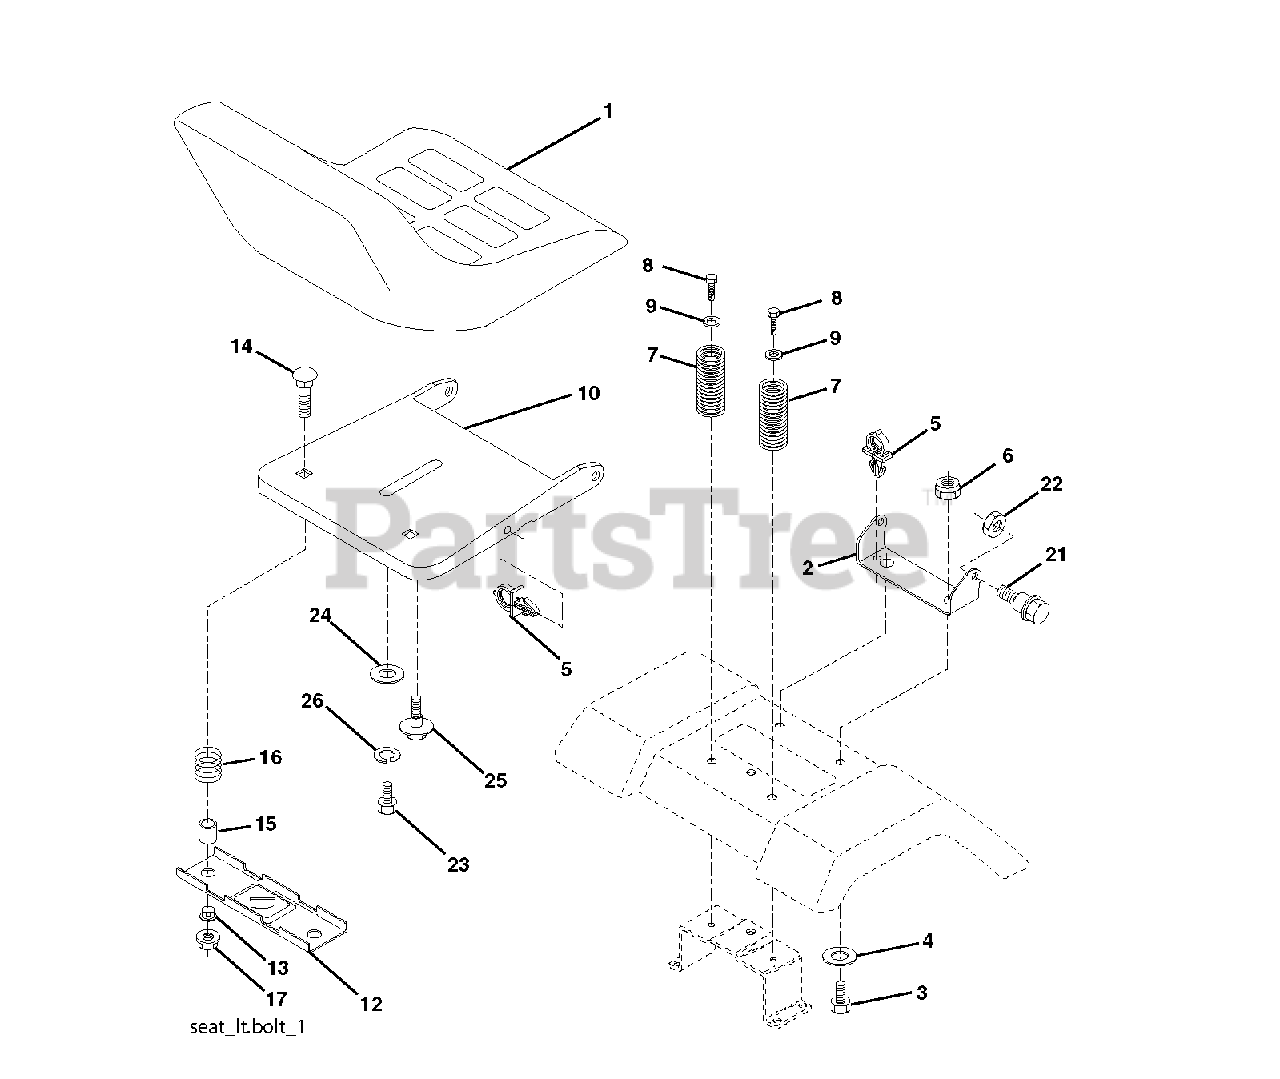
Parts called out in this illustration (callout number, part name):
1	SEAT.XG090.BLK.KB/BLT.NO-LOG
2	SEAT PIVOT BRKT
4	WASHER PM
5	PUSH CLIP
6	NUT
7	SPRING COMPRESSION
8	SCREW 3/8-16X1
9	WASHER
10	PAN.ASM.SEAT.1SLOT
12	BRKT.MNTNG.SWITCH.SEAT
14	BOLT.ROUND.HEAD.SQUARE.NECK
15	SPACER SPLIT 28X.96
17	NUT T
21	BOLT.SHOULDER.5/16-18
22	NUT.71038.31-18.HEX.NYLOCK
23	BOLT.HEX.BLACK
25	BOLT,SHOULD
26	LOCKWASHER
